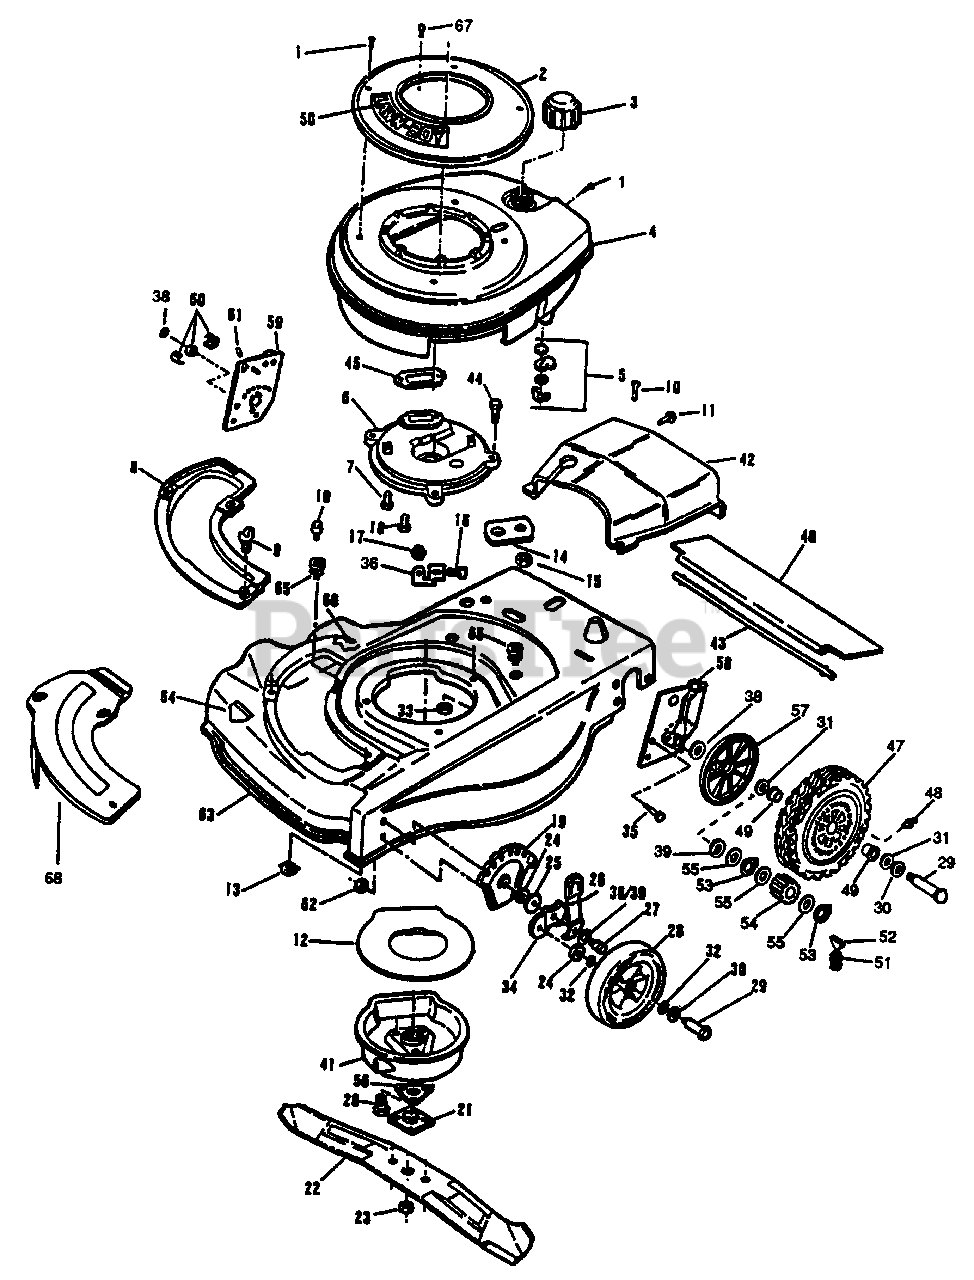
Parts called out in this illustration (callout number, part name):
1	Screw
2	Starter Base & Nut Assembly
3	Fuel Cap
4	Shroud-Engine (Inc. 4)
5	Fuel Shut-Off Assembly
6	Plate Muffler
7	Screw-Muffler Plate to Block
8	Cover Plate
9	Wing Screw
10	Screw-Plate & Chute Mounting
11	Screw-Sems
12	Baffle-Muffler
13	Caged Nut
14	Bolster-Housing
15	Nut-Bolster to Housing
16	Screw
17	Nut
18	Screw-Muffler Plate To Cylinder
19	Height Adjust Plate-Front
20	Screw-Muffler to Muffler Plate
21	Collar & Plate Assembly
22	Blade-21"
23	Nut-Blade
24	Washer
25	Washer-Wheel Mounting Brkt
26	Knob & Spring Height Adjust
27	Bolt-Shoulder
28	Wheel-Front
29	Bolt-Wheel
30	Washer-Flat
31	Washer-Felt
32	Washer-Felt
33	Nut-Muffler Plate to Housing
34	Height Adjust Bracket
35	Screw-Handle Bracket
36	Baffle Bracket
37	Screw-Bolster to Housing
38	Washer-Shim (.010)
39	Washer-Shim (.015)
40	Shield-Trailing
41	Muffler Cover
42	Cover-Drive
43	Rod-Trailing Shield
44	Screw-Muffler Plate to Housing
45	Gasket-Exhaust
46	Locknut-Hdl. Brkt. to Housing
47	Rear Wheel (Inc. 48-49)
48	Lube Fitting
49	Bushing
50	Applique-Starter Base
51	Spring
52	Key
53	Retaining Ring
54	Pinion
55	Spacer
56	Crankshaft Support
57	Cover-Rear Wheel
58	Height Adjuster Assembly-L.H. (Inc. 60-61)
59	Height Adjuster Assembly-R.H. (Inc. 60-61)
60	Bearing & Retainer Assy
61	Fitting
62	Nut
63	Housing Assembly (Inc. 64-66)
64	Decal-Blade Contacy Warning
65	Grommet
66	Decal-Discharge Area
67	Screw-Starter Mounting
68	Mulch Plate Accessory
